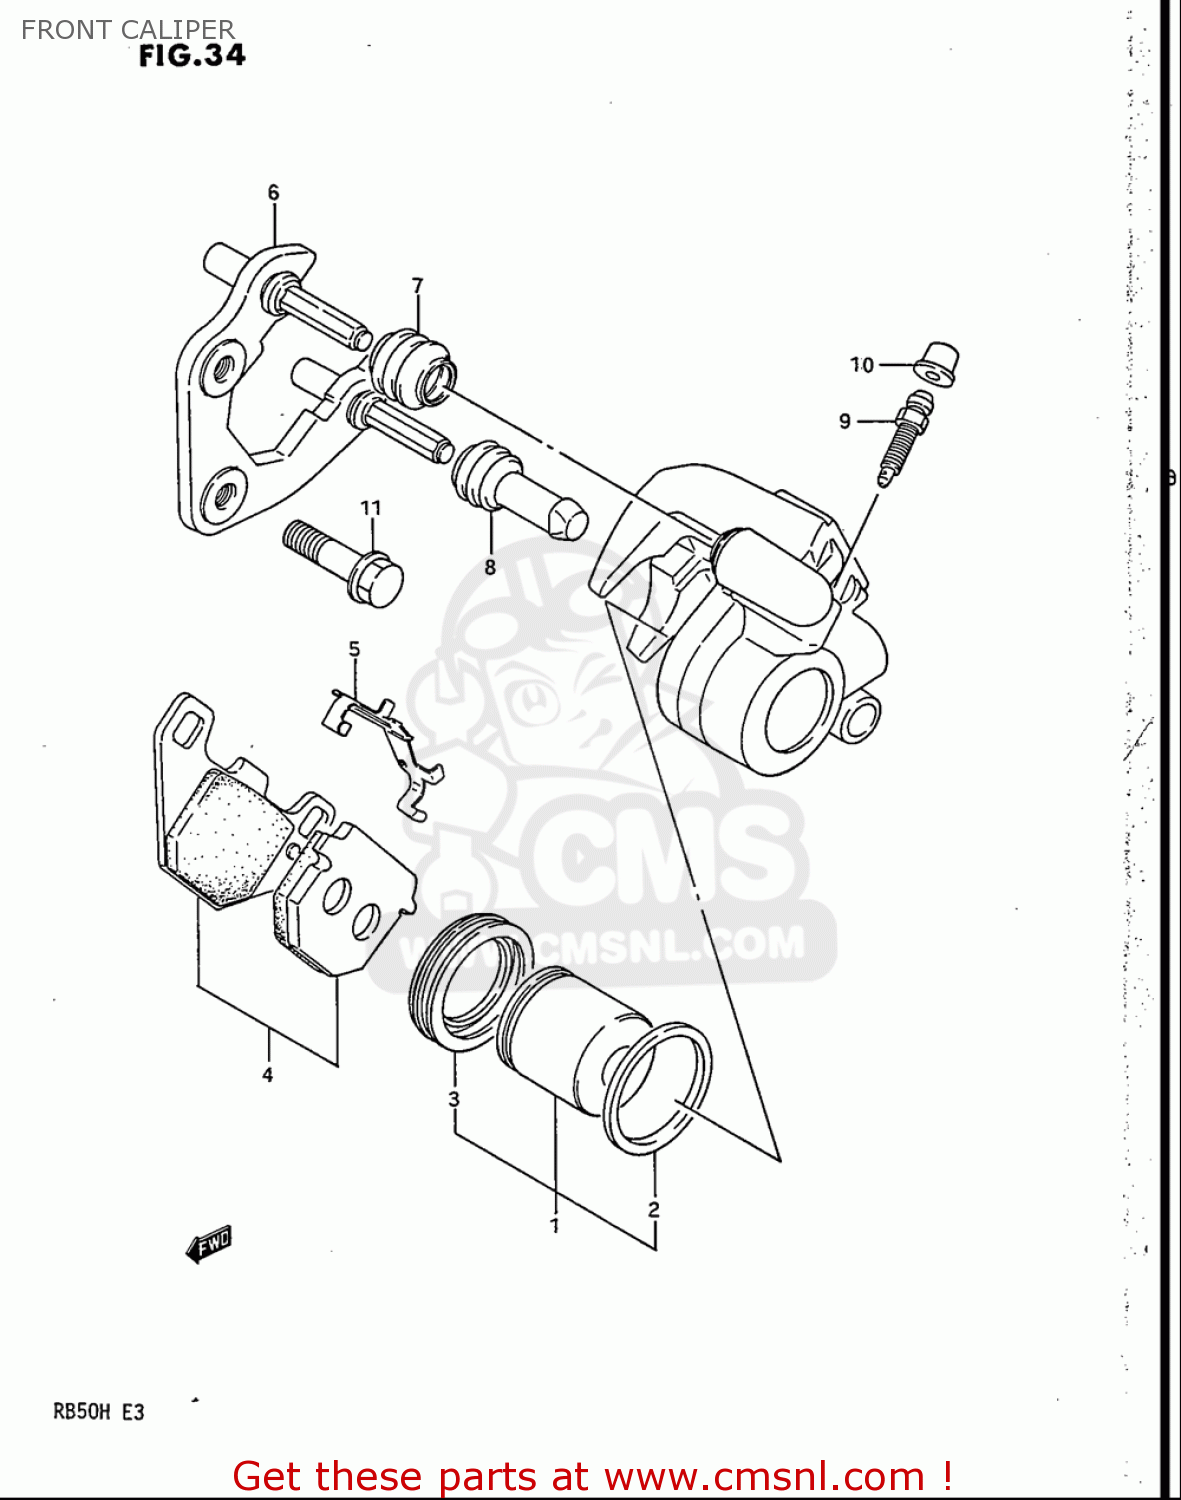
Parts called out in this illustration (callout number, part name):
1	PISTON SET
2	SEAL,PISTON
3	BOOT
4	PAD SET (NAS)
5	SPRING,PAD
7	BOOT,AXLE
8	INSULATOR,AXLE
9	BLEEDER
10	CAP,BLEEDER PLUG
11	BOLT
